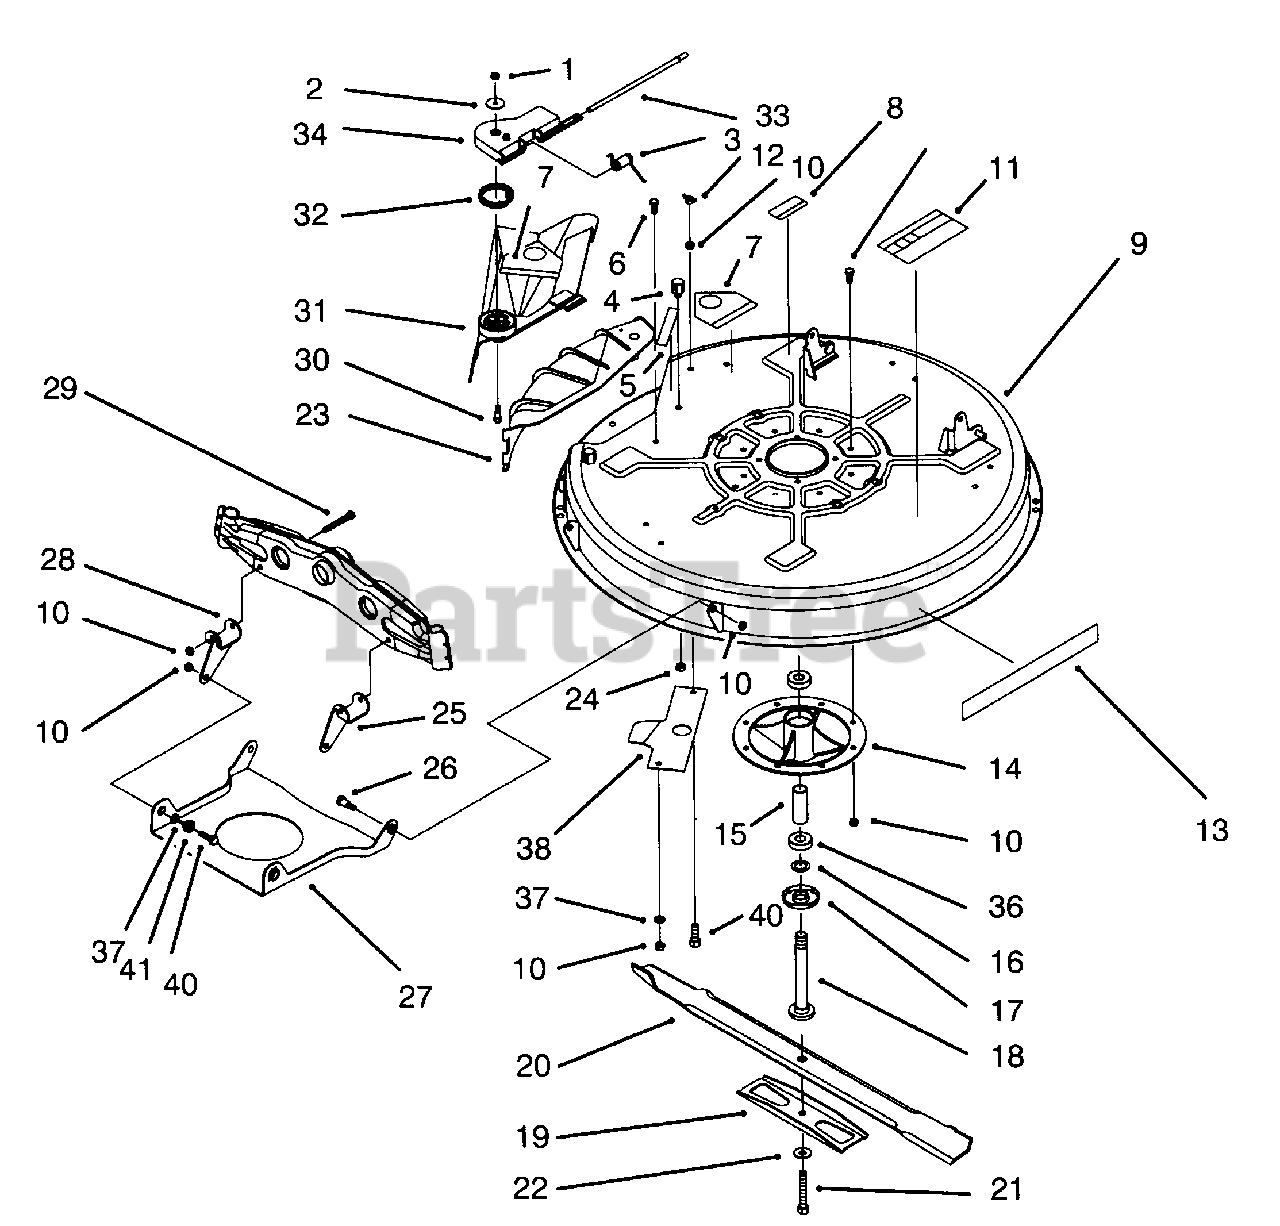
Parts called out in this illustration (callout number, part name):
1	Nut-Lock
2	Washer-Fender
3	Spring-Torsion
4	Post-Rear Pivot
5	Decal-Deflector Danger
6	Screw-Hex Hd. Cap
7	Decal-Danger
8	Decal-Caution
9	Cutter Deck-32"
10	Nut-Lock
11	Decal-Danger
12	Nut-Wing
13	Decal-32" Easy Mulch
14	Housing-Spindle
15	Spacer-Bearing
16	Spacer-Hardened
17	Shield-Bearing
18	Shaft-Spindle
19	Stiffener-Blade
20	Blade-32"
21	Bolt-Blade
22	Washer-Belleville
23	Discharge Cover Ass'y
24	Nut-Lock
25	Bracket-L.H.
26	Bolt-Shoulder
27	Pan-Front Suspension
28	Bracket-R.H.
29	Screw-Hex Hd. Cap
30	Bolt-Shoulder
31	Deflector-Double Pivot
32	Spring-Torsion
33	Rod-Deflector Hinge
34	Hinge-Deflector Danger
36	Bearing-Spindle
37	Washer-Flat
38	Ramp-Deflector
40	Screw-Hex Hd. Cap
